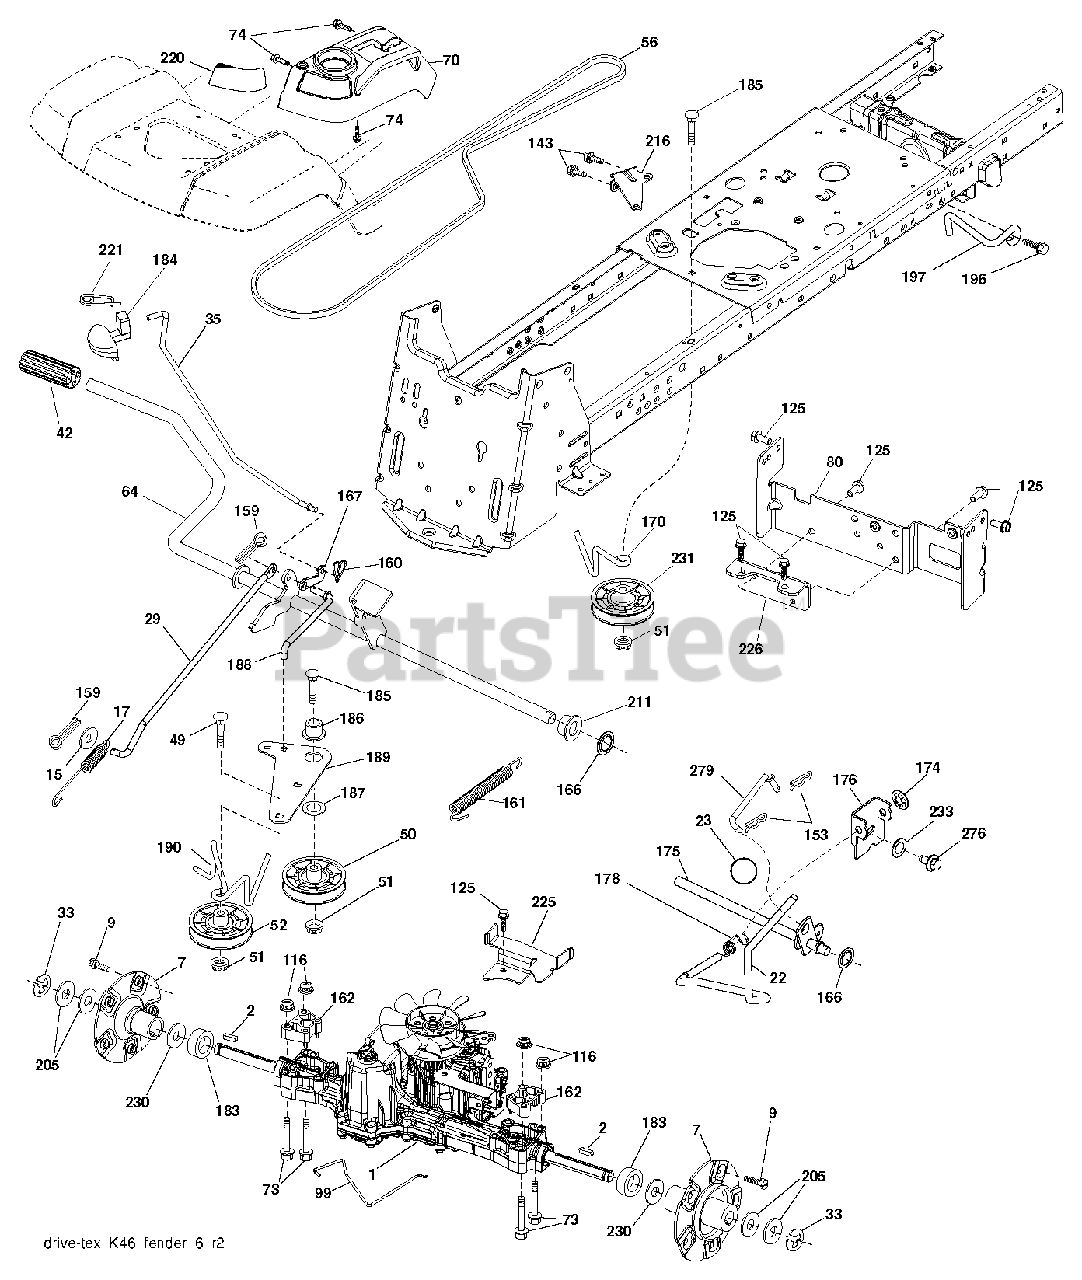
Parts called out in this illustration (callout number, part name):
1	Transaxle TUFFTORQ K46 AW
2	KEY.SQUARE.187X2.500
7	HUB.ASM.WHEEL.REAR.22"
9	HUB BOLT
15	WASHER
17	SPRING.BRAKE.K46.GREEN
22	ROD.SHIFT.FENDER.STGT.
23	KNOB.DELUXE.(PISTOL.GRIP).BLAC
29	ROD.BRAKE.K46
35	ROD.BRAKE.PARKING.GT.H
42	PEDAL COVER T
50	IDLER.FLAT.910.OFFSET
51	NUT LOCK FLG 3/8-16 UNC
52	IDLER.V-GROOVE.910.OFFSET
56	V-BELT.MOWER.92.40.42/K46
64	SHAFT.ASM.PEDAL.BRAKE.
70	RP CONSOLE.ASM.HYDO.HUSQ.
73	BOLT.HEX.FLNG.5/16-18X3.75
74	SCREW.HI-LO.CONSOLE
80	STRAP TORQUE
99	ROD.SPRING.BYPASS.K46.TEX.GT
116	NUT LOCK HEX FLANGE 5/16-18
125	SCREW
143	SCREW LT
153	RETAINER M
159	COTTER PIN
160	RETAINER CLIP
161	SPRING, RETURN LT
162	SPACER.TRANSAXLE.18&22
166	NUT.PUSH.625
167	LATCH.BRAKE.SPRING
170	KEEPER.CENTER SPAN.1.688
174	NUT.PUSH.500.2006
175	SHAFT ASM SHIFT
176	ARM.CLEVIS.ROD.SHIFT
178	SPRING.SHIFT.GT2006
183	SPACER.SPLIT.800X.350
184	HANDLE.PARKG.BRK.HUSQ X667
186	SPACER.RETAINER
187	WASHER 12/32X2X10GA
188	RP LINK.CLUTCH.GROUND.DRIVE
189	BELLCRANK.GROUND.DRIVE.TEX.
190	KEEPER.BELLCRANK.DRIVE
196	SCREW 3/8-16X1
197	BRKT.ANIT-ROTATION.CLUTCH
211	BUSHING.SHAFT.BRAKE.HAND
216	BRACKET.PULLEY.IDLER.W/TEX
220	REFLECTOR.RH.TEX GT
221	RETAINER.SPRING.CLIP.H
225	KEEPER.BELT.TRANSAXLE.K46
226	BRKT.MOUNT.TORQUE.K46.
230	WASHER.HARDENED
231	IDLER.V-GROOVE.1.688.OFFSET
233	WASHER SERRATED
276	BOLT FIN HEX 7/16-14 X 1
279	LINK.SHIFT.T/A.K46.FEND.TX
